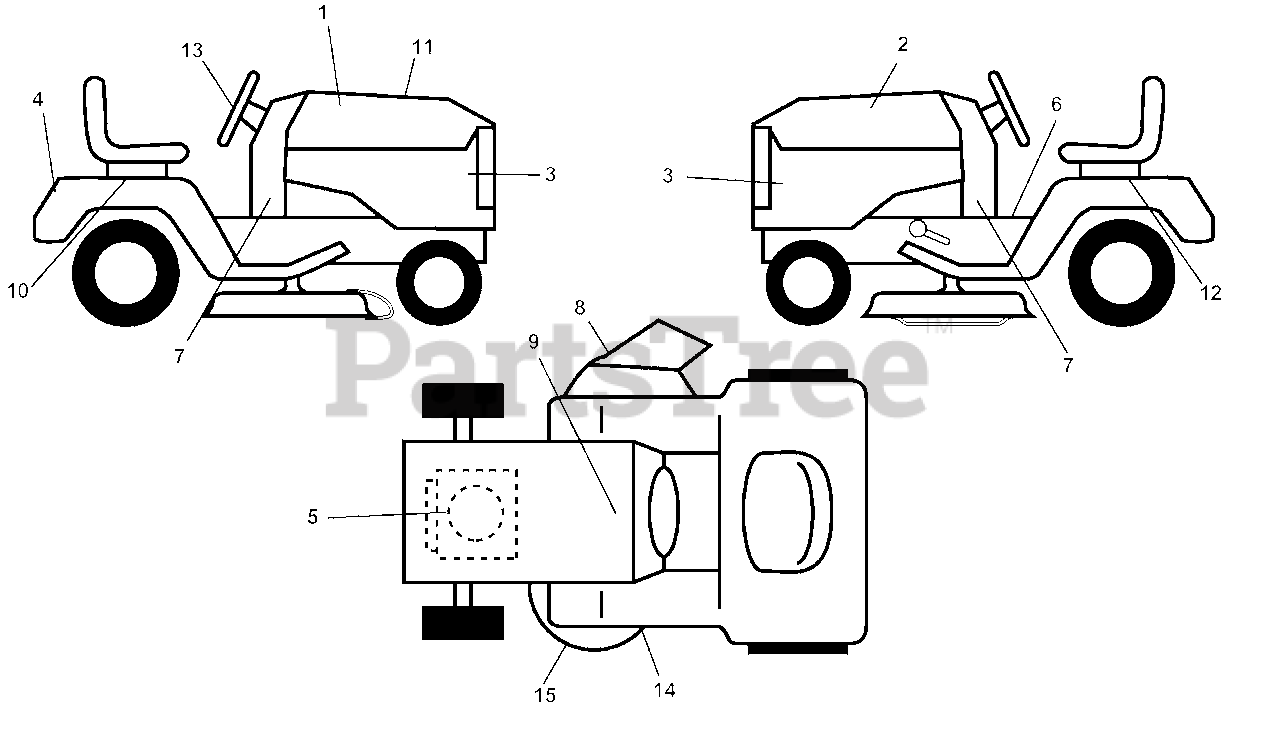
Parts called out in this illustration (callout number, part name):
1	Decal, Hood RH
2	Decal, Hood LH
3	Decal, Side Panel
4	Decal, Fender
5	Decal, Engine
6	Decal, Fender Operator's
7	Decal, Lower Dash
8	Decal, Warning
9	Decal, Battery Dnge/Poi
10	Decal Fender RH
11	Decal, Replacement
12	Decal Fender LH
13	Decal, Steering Wheel
14	Decal, Mower Schematic
15	Decal, Caution
15	Pad Foot Pedal Control
15	Decal, Bypass
15	Pad, Footrest, LH
15	Manual, Operator's (Eng/French)
15	Manual, Parts
